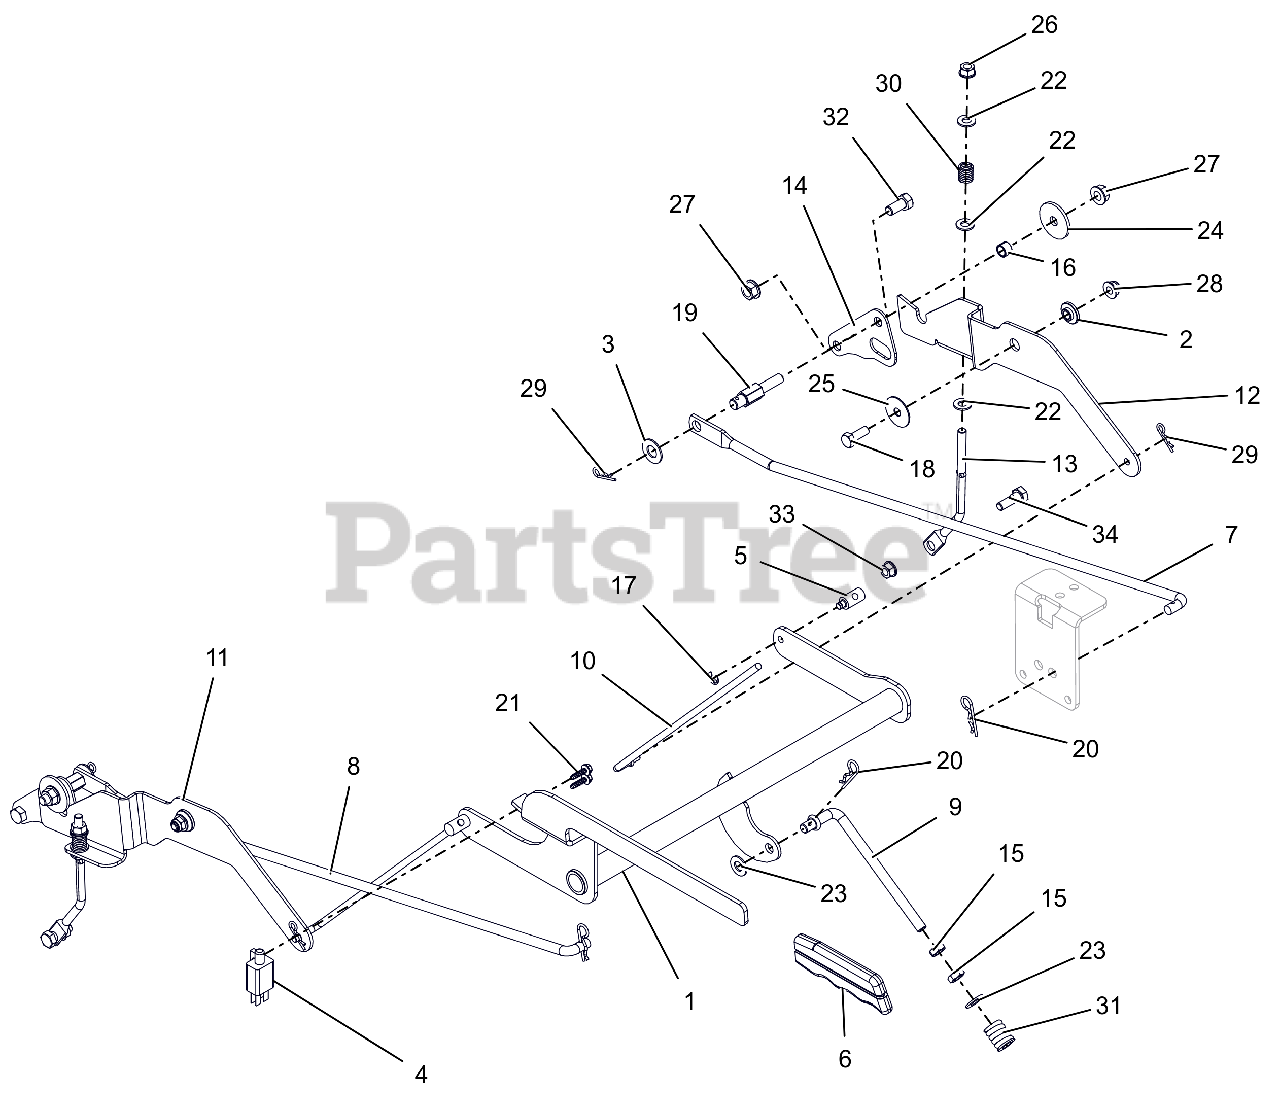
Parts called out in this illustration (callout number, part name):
1	WLDMT, BRAKE LEVER
2	BSHG, FLG .325X.499X.26X.88
3	WSHR, FLT .505X1.00X.062 ZCC
4	SWITCH- DOUBLE POLE N.O./N.O.
5	TRUNION, 1/4-20
6	GRIP, PARKING BRAKE (YELLOW)
7	ROD, STEERING LINKAGE LH
8	LINKAGE, STEERING - RH
9	LINK, OVER CENTER, PARKING BRK
10	ROD, PARK BRAKE
11	INTERLOCK, RH BRAKE LINK
12	INTERLOCK, LH BRAKE LINK
13	LINK, BRAKE (XL)
14	PLATE, TRANSAXLE ADAPTOR
15	NUT-JAM .375-16 G2 ZCC
16	SPCR, SLV .385X.500X.350
17	RG-RTNG-EXT .250X.025
18	BLT, HEX .31-18X.875 G5 ZCC
19	POST, STEERING LINK MOUNTING
20	PIN, HAIR .09 X 1.50 ZCC
21	SCR, PLASTITE-HWH 0.2 X 0.75 ZC120
22	WSHR,FLT .344X.688X.065 ZCC
23	WSHR,FLT .406X.812X.065 ZCC
24	WSHR, FLT .380X1.50X.125 ZCC
25	WSHR, FLT .347X1.254X.048 ZCC
26	NUT,LK-CTR-FLG .31-18 GF ZCC
27	NUT-LK-CTR-FLG .375-16 GF ZCC
28	NUT,NYL-FLG .31-18 GF ZCC
29	PIN, HAIR #213 .08X1.19 ZCC
30	SPRING, COMPRESSION
31	SG-COMP .187X.56X1.62
32	BLT,HEX .38-16X.75 G5 ZCC
33	NUT-LK-TOP-FLG .312-18 GF ZCC
34	BOLT,SHLDR .38X.25 -.31-18X.75
